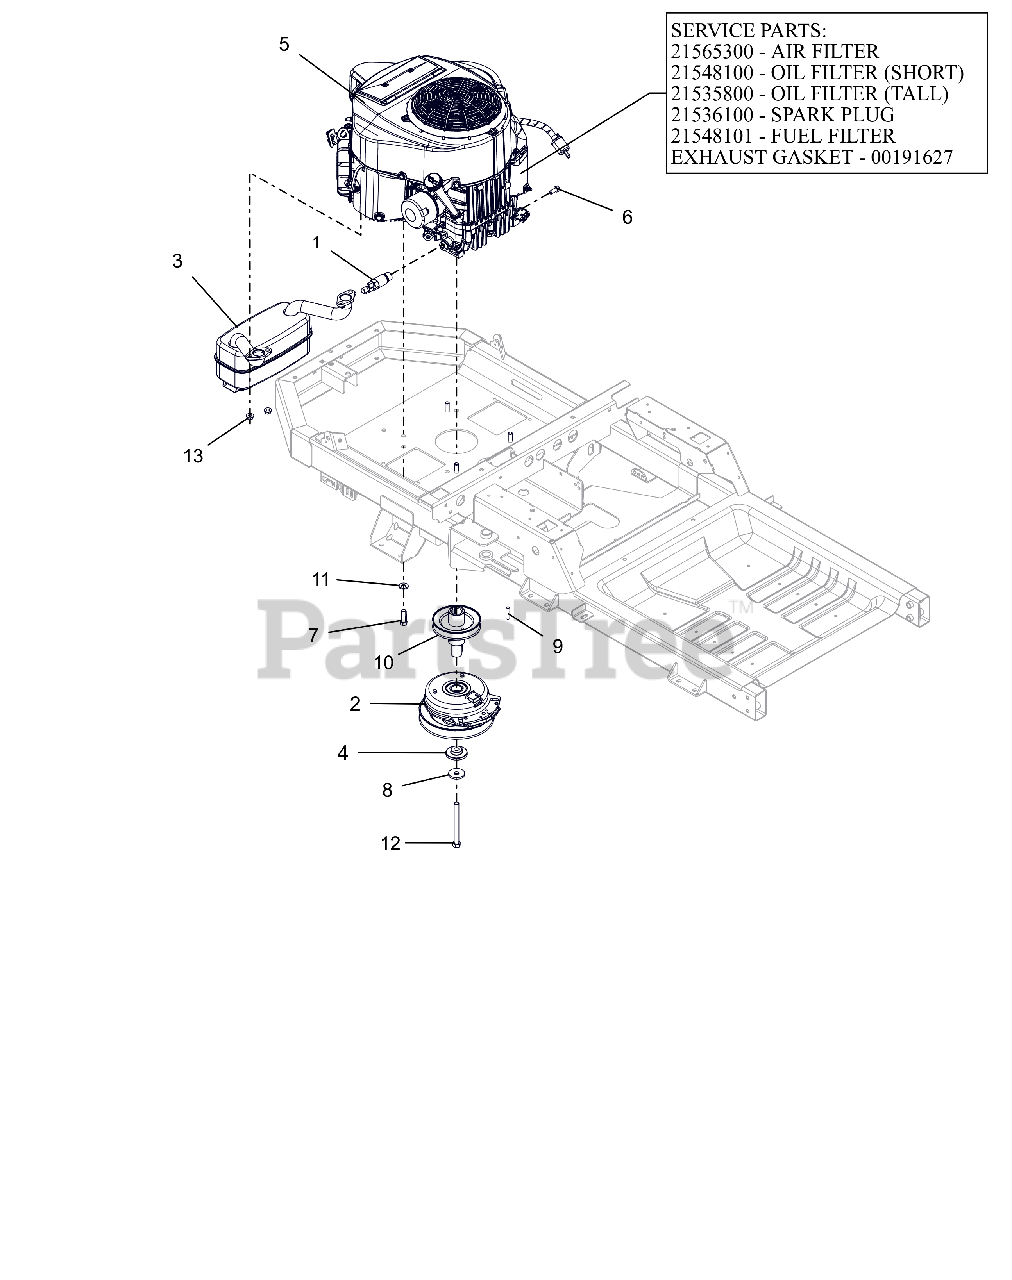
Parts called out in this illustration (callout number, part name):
1	DRAIN, OIL M20X2.5
2	CLUTCH,105FTLB MONOPOLE 6.83"
3	MUFFLER - KAWASAKI
4	BSHG-FLG .469X1.06X.574X2.0
5	ENGINE, KAWASAKI FR600
5	AIR FILTER, KAWASAKI FR
5	OIL FILTER, KAWASAKI FR
5	FILTER,OIL - KAW
5	PLUG, SPARK
5	FUEL FILTER-KAWASAKI FR
5	GASKET, MUFFLER S/O
6	BLT, HEX M8-1.25X20 G8.8 ZCC
7	BLT, HEX .38-16X1.25 G5 ZCC NT
8	WASHER, 7/16" SPRING DISK
9	KEY-SQ .25 X 1.25 X .25 SAE
10	WLDMT, DRIVE SHEAVE-X
11	WASHER, 3/8" SPRING DISC
12	BLT, HEX .44-20X4.50 G8 ZCC NT
13	NUT-LK-TOP-FLG M8 ZCC
